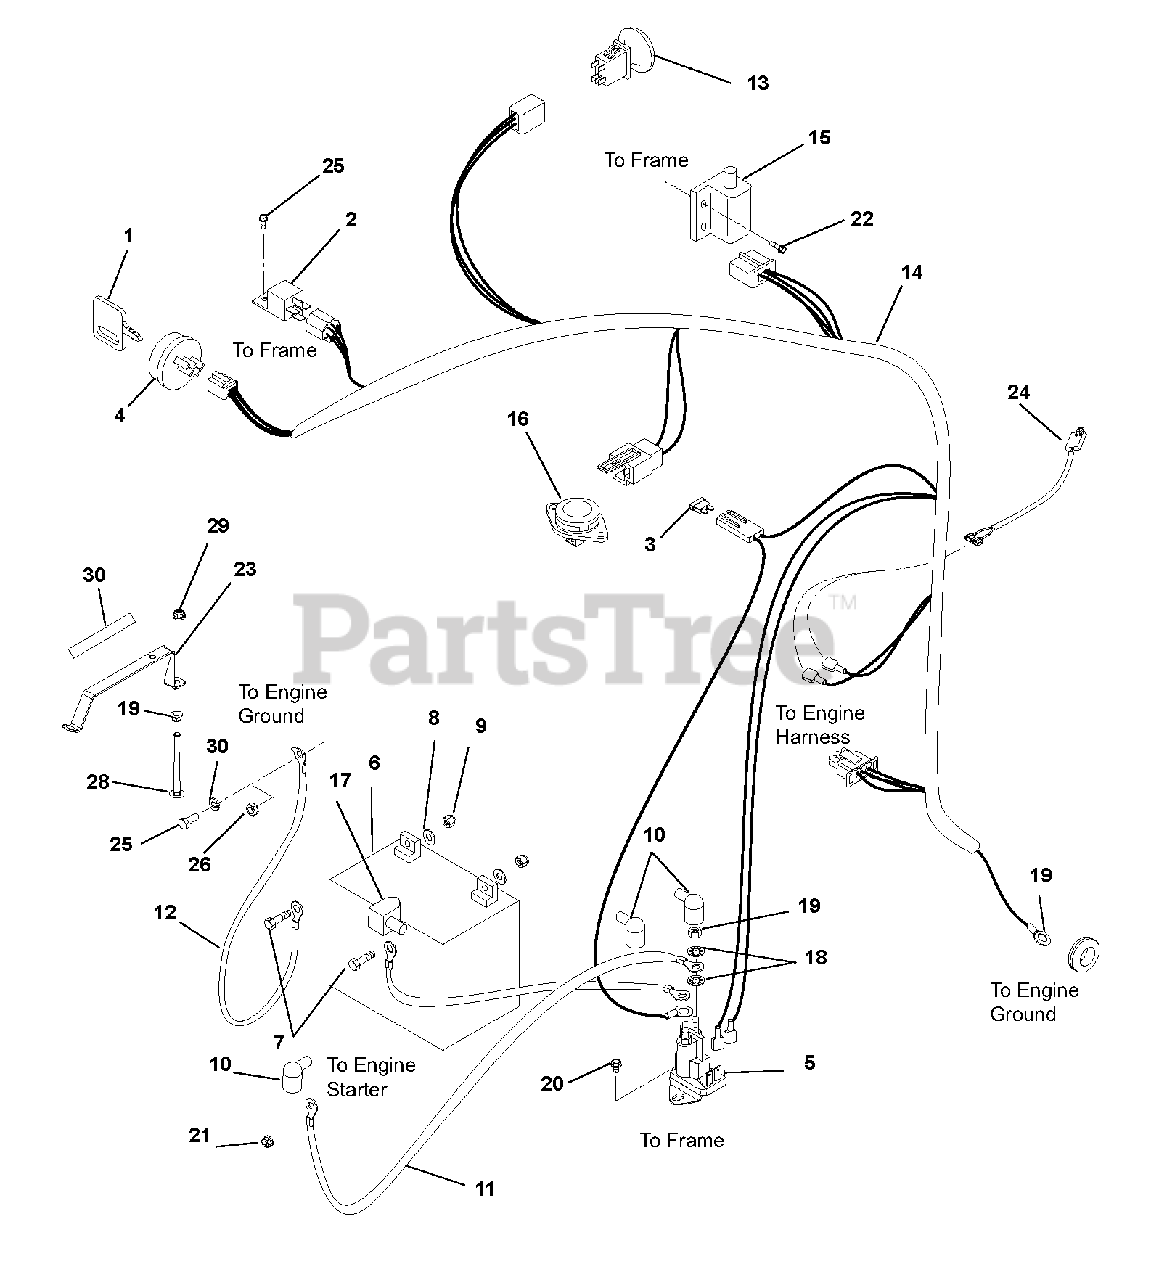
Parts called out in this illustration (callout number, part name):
2	Relay
3	Fuse, 30 AMP
4	KEYSWITCH-IGNITION 3 POS
5	Solenoid
6	Battery, 12V 20 Hour (Can be replaced with U1 190 or larger)
7	Bolt, Hex .25-20 x .75
8	Washer, Flat Steel .281 x .62 x .065
9	Nut, KEPS .250-20
10	Boot, Eyelet Terminal
11	Cable, POS
12	Ground Cable
13	Switch, Clutch With Retainer
14	Harness, Wiring ZT
15	Switch, Double Pole N.O. / N.O.
16	Switch, Snap Mounting (N.O.)
17	Insulator
18	Washer, Locking .31
19	Nut, Jam .31-24
20	Screw, Tapping .250-20 x .37 Hex Washer Head
21	Nut, Locking Top Flange .25-20
22	Screw, 12-14 x .75 HX
23	Hold Down, Battery
24	Harness, Clutch
25	Screw, Tapping 12-24 x .50 Hex Washer Head
26	Nut, Locking Center Jam .375-16 (915327)
27	Wire Clip (915328)
28	Bold, Round Head Square Neck .25-20 x 4.50
29	Nut, Locking Nylon Flange .25-20
30	Decal, U1 Battery Replacement
